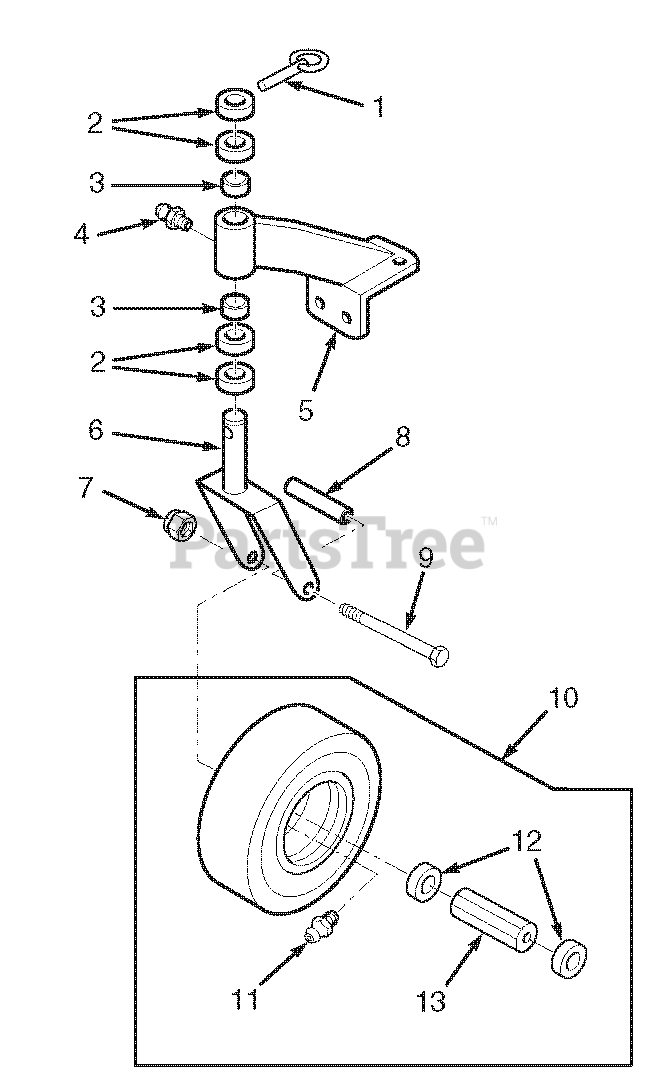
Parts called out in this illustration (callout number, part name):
1	Quick Pin
2	Spacer, Spacer Yoke, 1/2" Long
3	Bronze Bearing
4	Greasing Fitting
5	Support Assembly
6	Caster Yoke
7	Nut, Elastic Stop 1/2-13
8	Sleeve, Caster Wheel Bearing
9	Bolt, Hex Head 1/2-13 x 5-1/2"
10	Flat-Free Tire Assy.
11	Grease Fitting, 45 Degree 1/4-28
12	Retainer, Caster Wheel Bearing
13	Roller Bearing, Caster Wheel
